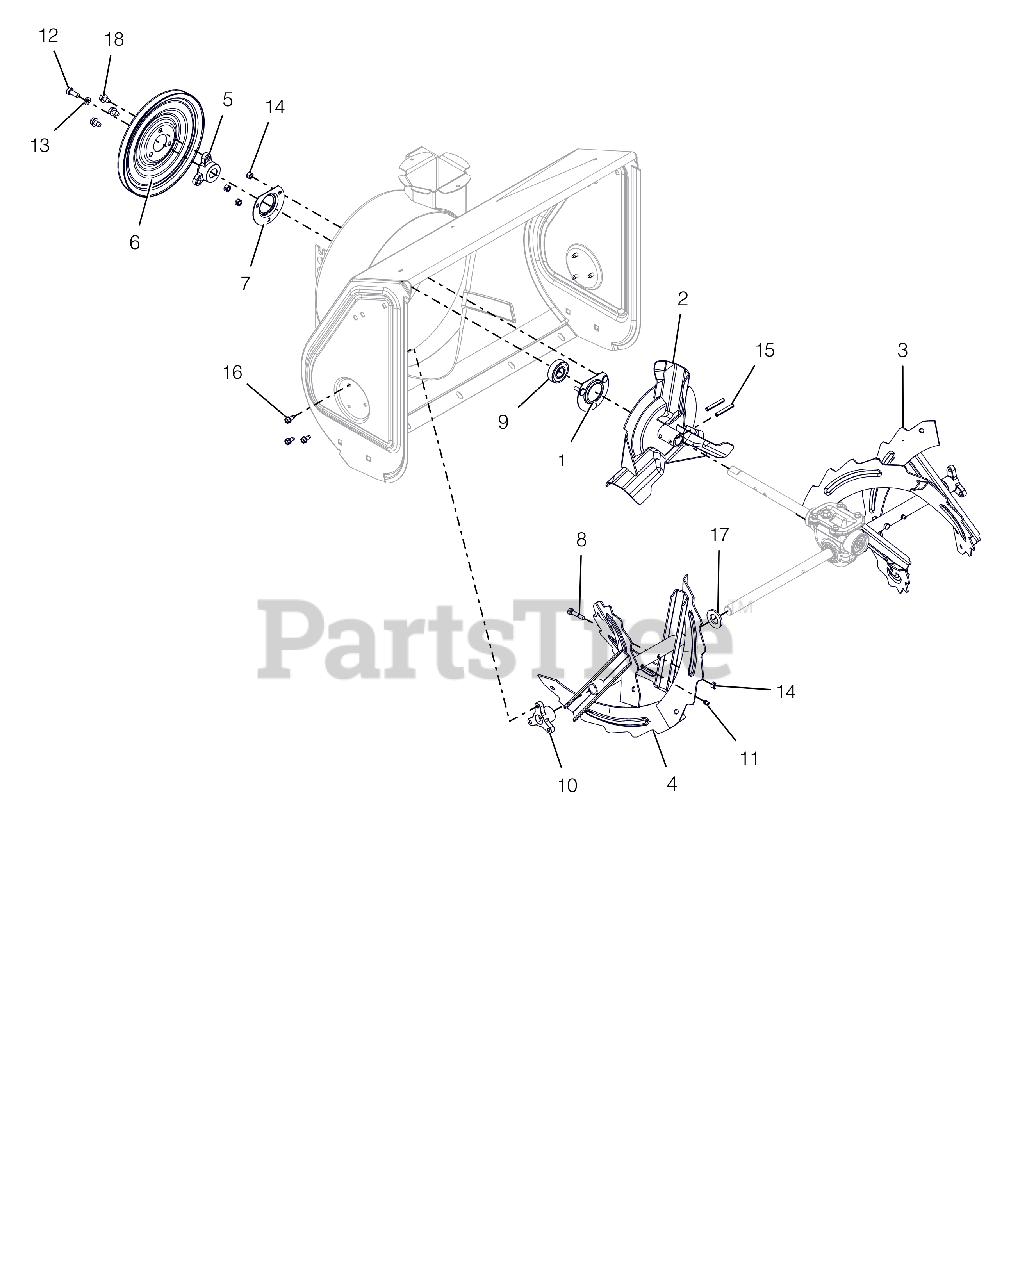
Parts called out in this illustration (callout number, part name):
1	BEARING FLANGE
2	IMPELLER, COMPACT 12" 3-BLADE
3	RAKE, 24" LH, BLK SERR W/ZERK
4	RAKE, 24" RH, BLK SERR W/ZERK
5	PULLEY HUB, BOLT-ON D-BORE .75
6	PULLEY,SPIN FORM SINGLE GROOVE
7	BEARING FLANGE
8	SHEAR BOLT
9	BRG-BALL .750X1.750X.50
10	BUSHING, RAKE SHAFT .75"
11	ZERK,FITTING .25X.125 DRIVE IN
12	BLT-HEX .31-24X.75 YWZC GR5
13	WSHR-LK .312X.097 HVY YWZC
14	@NUT-LK-CTR .25-20 YWZC
15	PIN-ROLL .250X1.75
16	SCR-TAP .25-20X.50 HWH TR YWZ
17	@WSHR-FL-STL.812X1.50X.135YWZC
18	@SCR-TAP .31-18X.50 HWH TR YWZ
